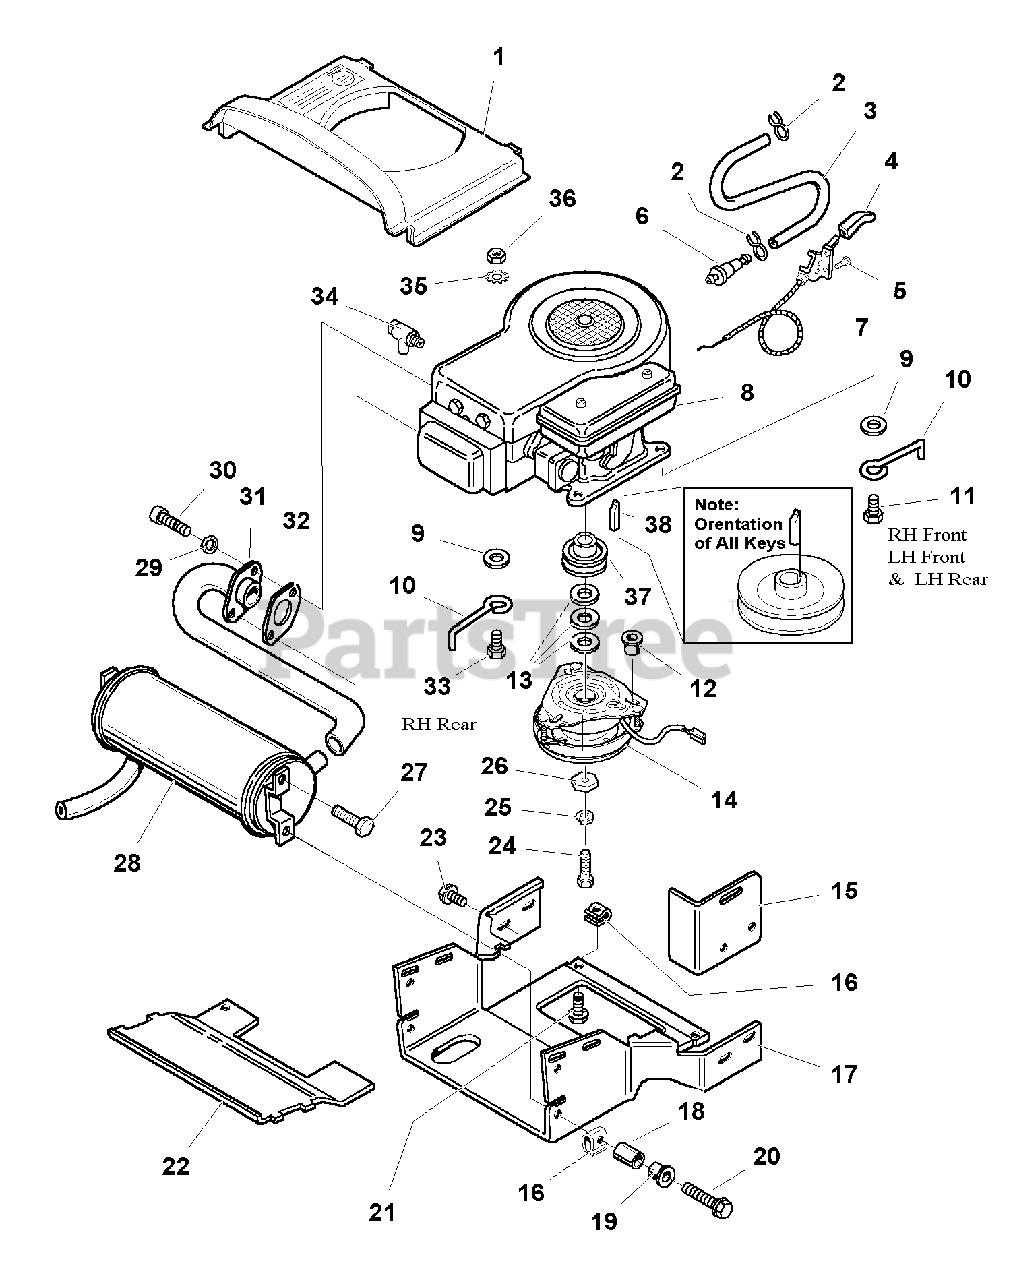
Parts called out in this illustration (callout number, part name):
1	PLENUM, Inlet
2	CLAMP, Hose
3	HOSE, Fuel, Cut to 12" length
4	KNOB, Throttle Control
5	CAPSCREW, Hex Head, Plastite, 1/4-14 x 5/8
6	FILTER, Fuel
7	CONTROL ASSEMBLY, Throttle
9	WASHER (16HP Units Only)
10	GUIDE, Belt, Wireform
11	CAPSCREW, Hex Head, Taptite 3/8-16 x 1-1/2
12	SLEEVE, Clutch Anchor
14	** CLUTCH, Electric
15	PLATE, Muffler Duct
16	PAL NUT, 5/16-18
17	DUCT, Muffler, Lower
19	PIVOT, Hood
20	CAPSCREW, Hex Head, Whizlock, 5/16-18 x 1-1/4
21	CAPSCREW, Hex Head, Whizlock, 5/16-18 x 3/4
22	DUCT, Muffler, Upper
23	CAPSCREW, Hex Head, Taptite, 5/16-18 x 1/2
24	CAPSCREW, Hex Head, 7/16-20 x 3
25	LOCKWASHER, 7/16
26	WASHER, Hex
27	CAPSCREW, Hex Head,Taptite, 1/4-20 x 3/8
28	MUFFLER ASSEMBLY (Includes Ref. No. 31)
29	LOCKWASHER, 5/16
30	CAPSCREW, Socket Head, 5/16-18 x 3/4
31	PIPE, Exhaust
32	GASKET, Muffler
33	CAPSCREW, Hex Head, Taptite, 3/8-16 x 2
34	DRAIN VALVE, Oil
35	WASHER, External Tooth 3/8
36	NUT, Hex, Jam Lock, 3/8-16
38	KEY, Hi-Pro
